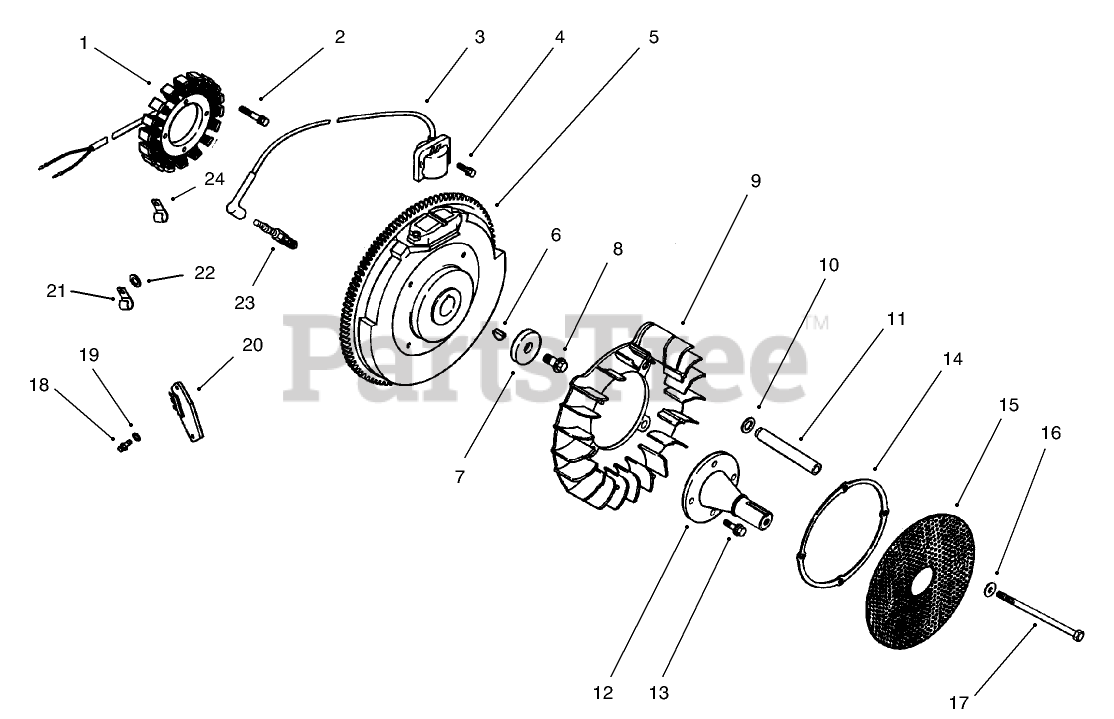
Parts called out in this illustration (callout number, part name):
1	Stator Kit, 15 Amp
2	Screw
3	Module-Ignition
4	Screw
5	Flywheel Assembly
6	Key
7	Washer
8	Screw
9	Fan (Only On: 72103, 72083)
10	Washer, sping
11	Spacer
12	Shaft, front drive
13	Screw M8x1.25x22 (Only On: 72042, 72043, 72062, 72063)
14	Ring-Support
15	Screen-Grass
16	Washer
17	Screw-Hex
18	Screw
19	Washer
20	Rectifier-Regulator
21	Clip
22	Washer
23	Spark Plug
24	Clip
